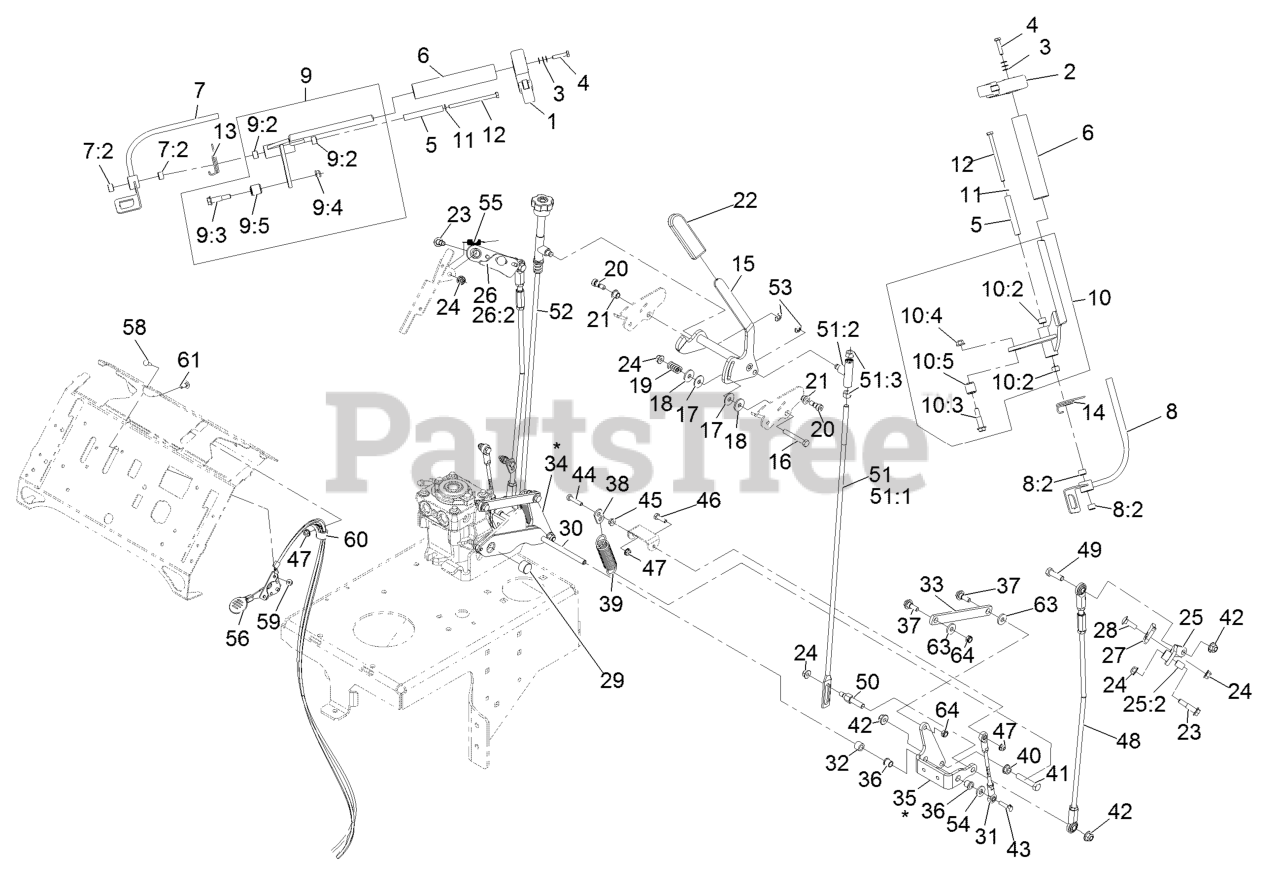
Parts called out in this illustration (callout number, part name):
1	ASM,LATCH RH THUMB
2	ASM,LATCH LH THUMB
3	WASHER-SPRING
4	SCREW-HH
6	GRIP-BAR, HANDLE
7	OPC-W/BUSHING, RH
7:2	BUSHING-SLEEVE
8	OPC-W/BUSHING, LH
8:2	BUSHING-SLEEVE
9	ASM, CONTROL-RH
9:2	BUSHING-SLEEVE
9:3	SCREW-SHOULDER
9:4	NUT-HF, NI
9:5	ASM, ROLLER
10	ASM, CONTROL
10:2	BUSHING-SLEEVE
10:3	SCREW-SHOULDER
10:4	NUT-HF, NI
10:5	ASM, ROLLER
11	SCREW-HH
12	SCREW-HH
13	SPRING, TORSION
14	SPRING, TORSION
15	SPEED CONTROL ASM
16	SCREW-HH
17	WASHER-FRICTION
18	WASHER-FRICTION
19	SPRING-COMPRESSION
20	SCREW-HSH
21	BUSHING
22	GRIP-HANDLE, STEERING
23	SCREW-SHOULDER
24	NUT-HF, NI
25	ARM ASM-LEFT
25:2	SLEEVE-BEARING
26	ARM ASM -RIGHT
26:2	SLEEVE-BEARING
28	BOLT-CARR
29	PIN-BELLCRANK LINK RETAIN
30	BELLCRANK LINK ASM
31	ASM, LINK
32	SPACER-WHEEL
33	LINK-BELLCRANK, PUMP
34	BELLCRANK-LOWER, RT
35	BELLCRANK-LOWER, LT
36	BEARING
37	SCREW-SHOULDER
38	ANCHOR, SPRING
39	SPRING-EXTENSION
40	NUT-HHF, WHIZ
41	SCREW-HH
42	NUT-HF, NI
43	SCREW-HHF
44	SCREW-HH
46	SCREW-HH
48	ASM, ROD
49	SCREW-HH
50	STUD-CONTROL, SPEED
51	ASM, ROD LEFT
51:1	ROD, LEFT
51:3	NUT-HEX
52	ASM, ROD RIGHT
53	RING-RETAINING
54	WASHER-FRICTION
55	SPRING-EXTENSION
56	CONTROL-THROTTLE
58	BOLT-CARR
59	NUT-LOCK, FLANGE
60	CLAMP-CABLE
61	SCREW-CARR
63	WASHER-FLAT
64	NUT-LOCK, NI
